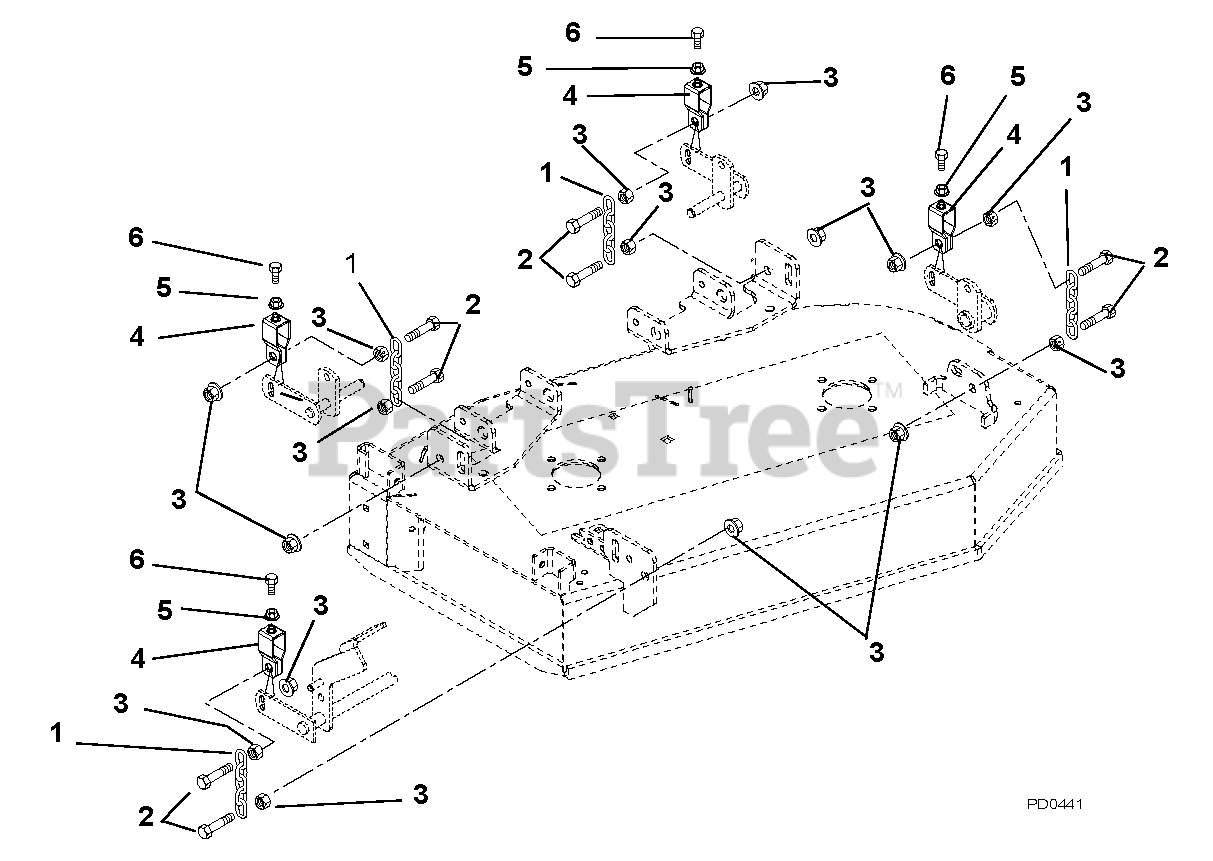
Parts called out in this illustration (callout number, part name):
1	Chain, Link
2	Bolt, Hex M12-1.75 x 50 CLS8.8
3	Nut, Spin Lock Flange M12-1.75
4	Bracket, Deck Leveling
5	Nut, Jam .312-18
6	Bolt, Hex .312-18 x 2.00 Full Thread
